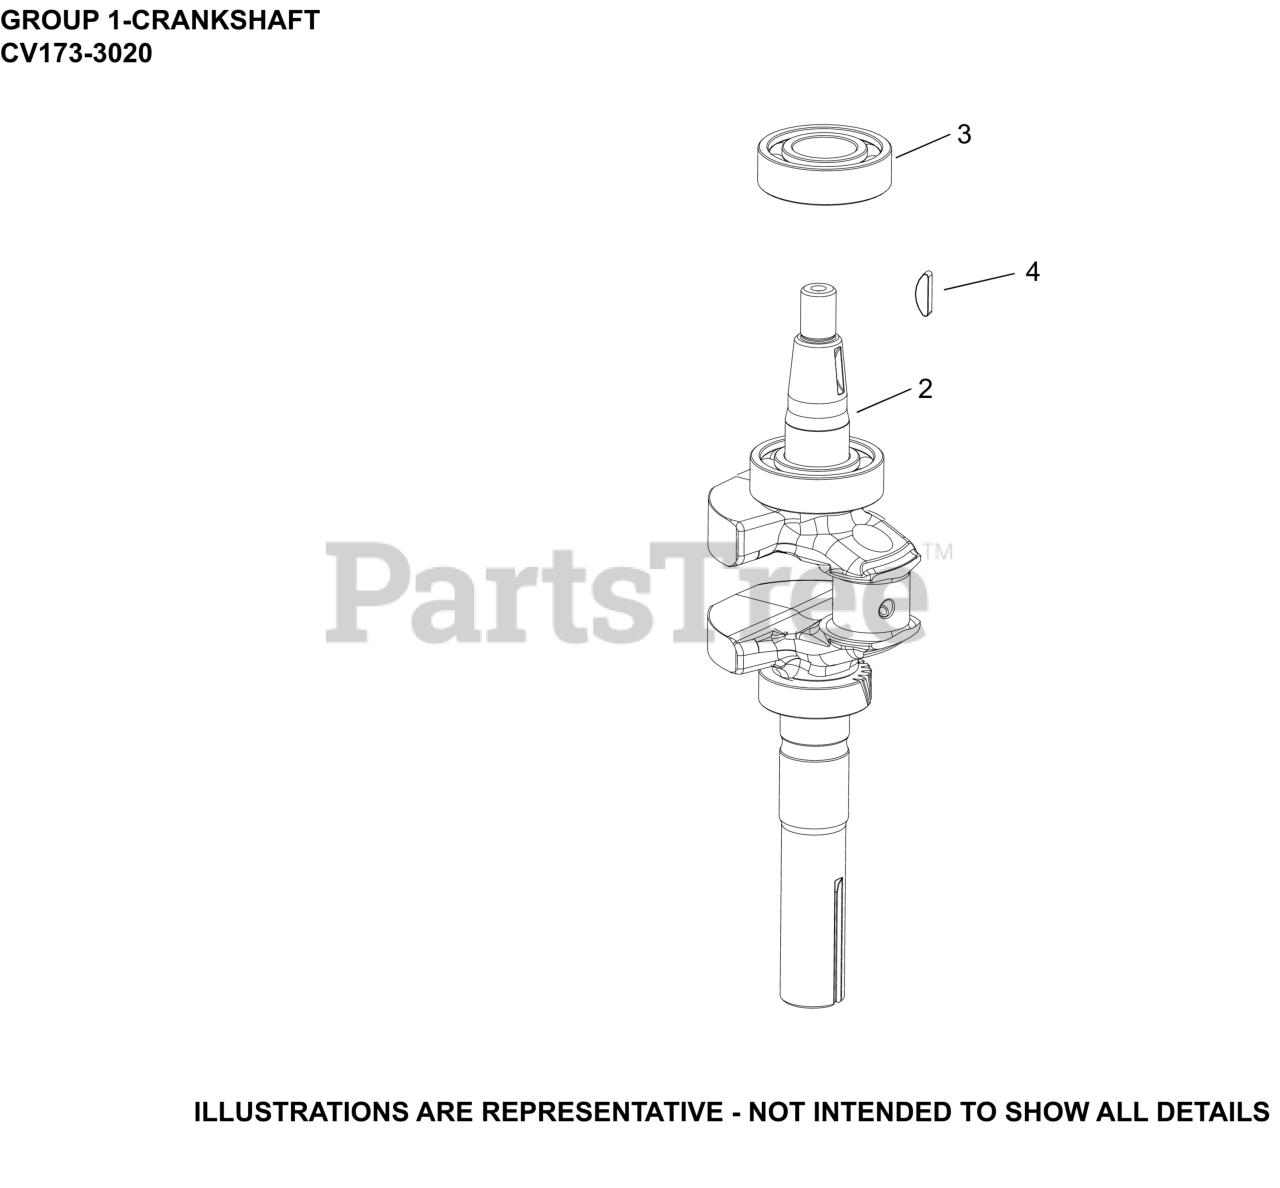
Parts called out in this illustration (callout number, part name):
2	CRANKSHAFT, ASSEMBLY
3	BEARING, BALL
4	KEY, FLYWHEEL
